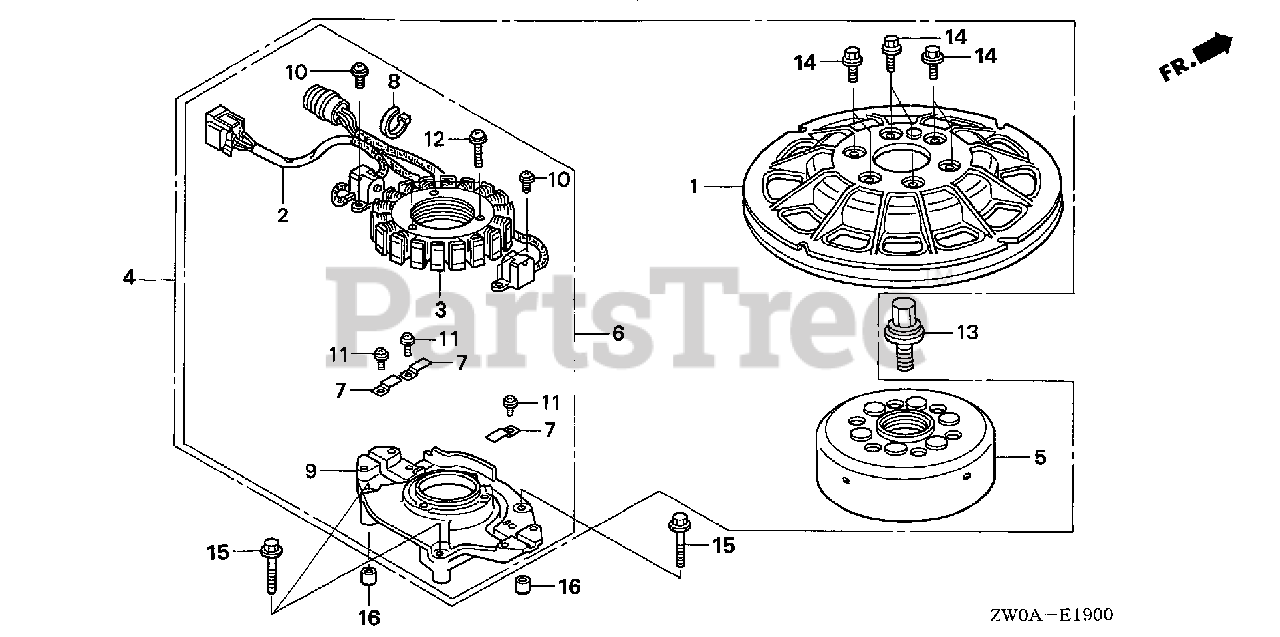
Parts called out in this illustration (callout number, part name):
1	PULLEY, STARTER
2	COIL ASSY., PULSER
4	ALTERNATOR ASSY.
6	STATOR ASSY.
7	CLAMP, WIRE
8	CLAMP, CABLE
9	BASE, COIL SETTING
10	SCREW-WASHER (5X12)
11	SCREW-WASHER (4X8)
12	SCREW-WASHER (6X30)
13	BOLT-WASHER (14X36)
14	BOLT, FLANGE (6X18)
15	BOLT, FLANGE (6X42)
16	PIN, DOWEL (8X10)
